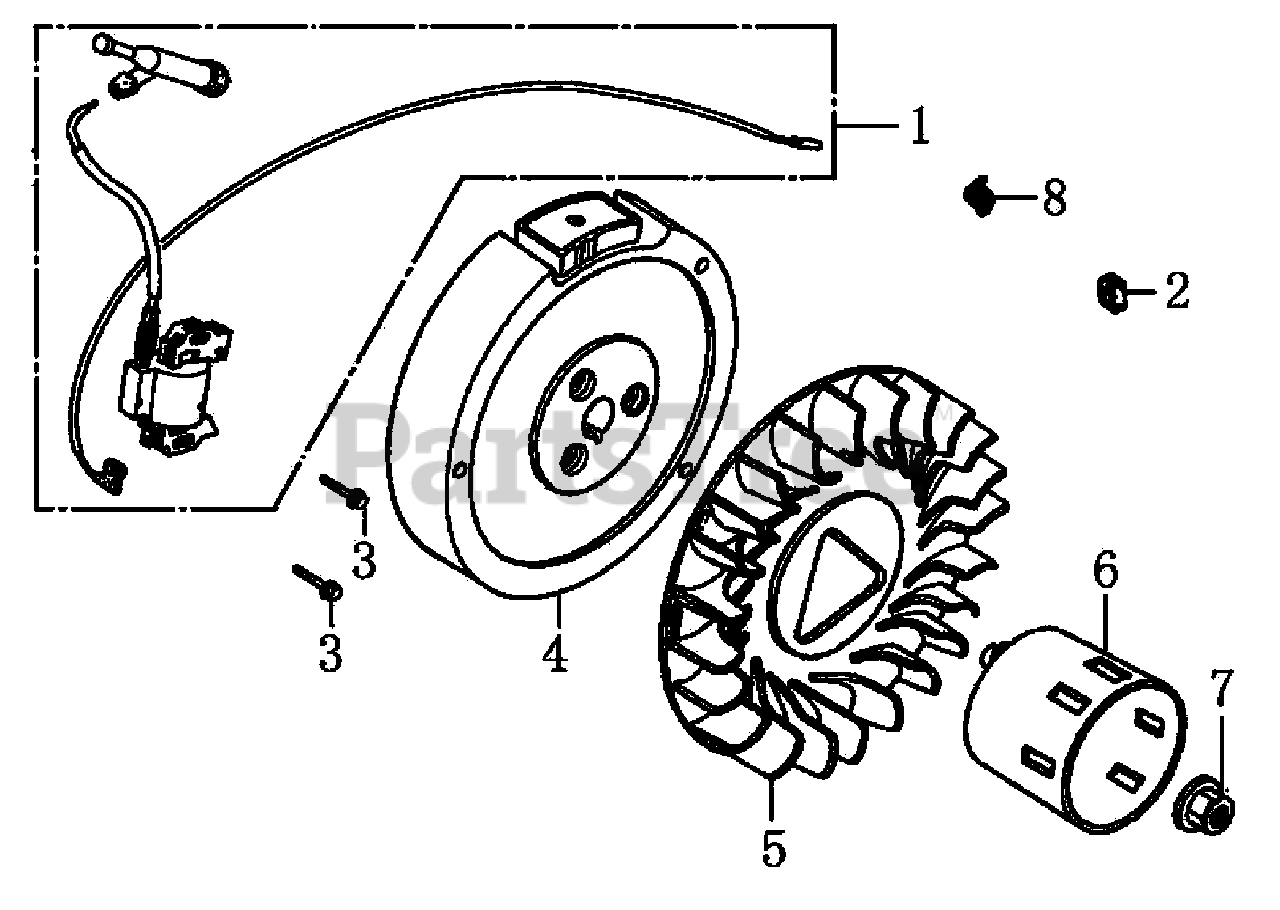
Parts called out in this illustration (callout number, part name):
1	COIL ASSY., IGNITION
2	GROMMET, CORD
3	BOLT, FLANGE, M6X25
5	FAN, COOLING
6	PULLEY, STARTER
7	NUT, SPECIAL, 16MM
8	HOLDER, STOP SWITCH
